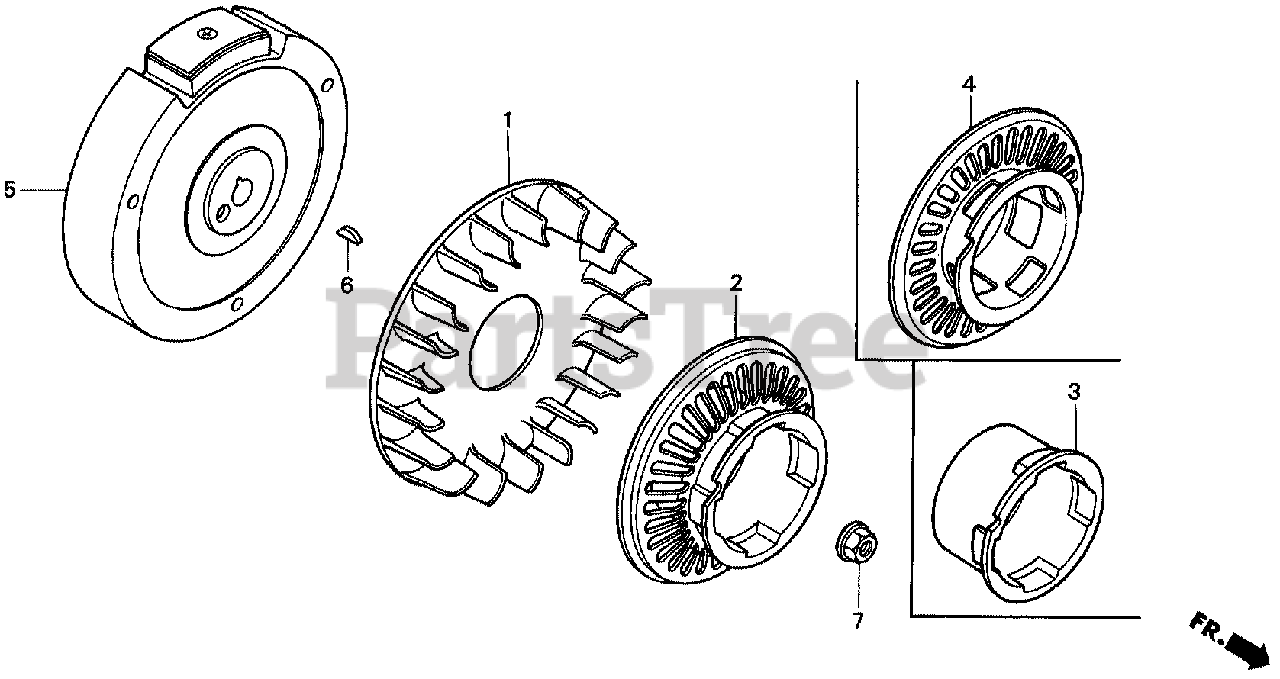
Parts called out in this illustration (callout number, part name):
1	FAN, COOLING
2	PULLEY, STARTER
5	FLYWHEEL
6	KEY, WOODRUFF (3X5)
7	NUT, FLANGE (12MM)
